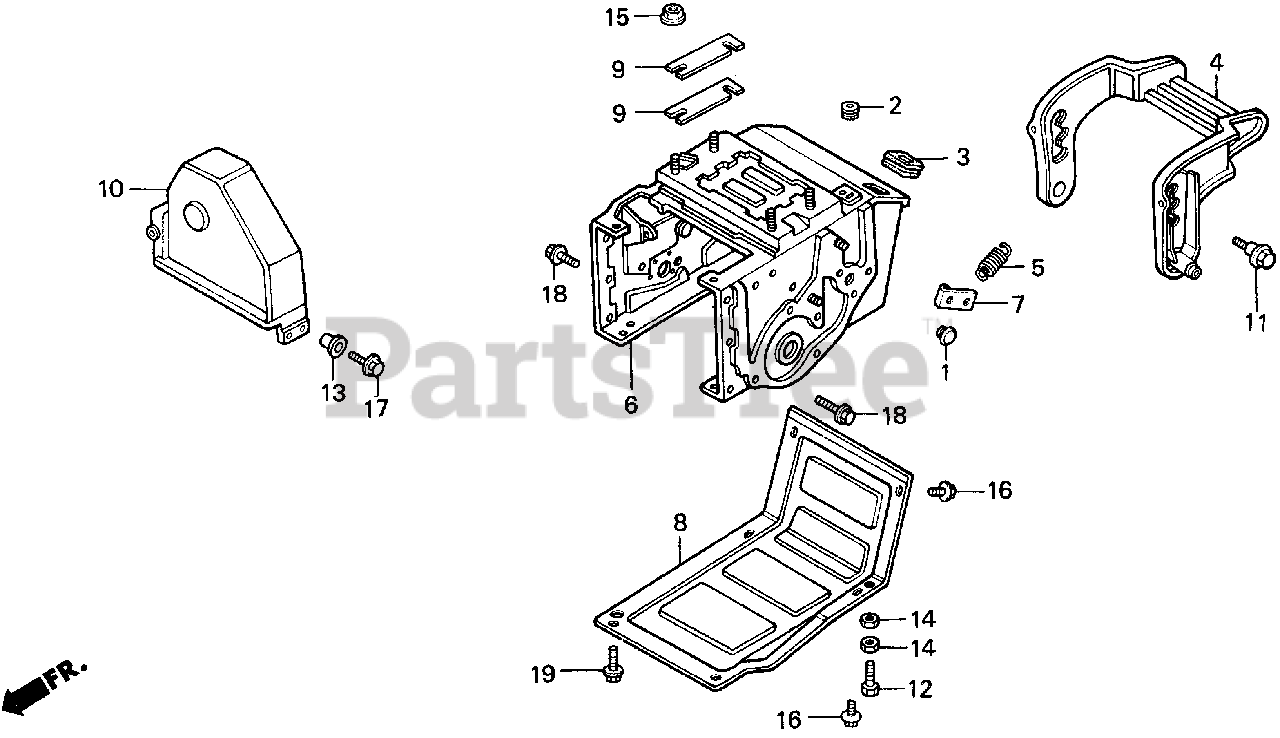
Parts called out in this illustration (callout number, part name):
1	GROMMET, GUIDE ROLLER
2	GROMMET A, TUBE
3	SEAL, CHANGE ROD
4	PLATE, HEIGHT ADJUSTING (NOT AVAILABLE)
5	SPRING, HEIGHT ADJUSTING
6	BED, ENGINE
7	HOOK, SPRING (NOT AVAILABLE)
8	COVER (LOWER) (NOT AVAILABLE)
10	COVER, BELT (NOT AVAILABLE)
11	BOLT, HEIGHT ADJUST SETTING
12	BOLT, ADJUSTING
13	WASHER, CHAIN CASE SETTING
14	NUT, HEX. (8MM)
15	NUT, FLANGE (10MM)
16	BOLT, FLANGE (6X10)
17	BOLT, FLANGE (6X14)
18	BOLT, FLANGE (8X16)
19	BOLT, FLANGE (8X40)
